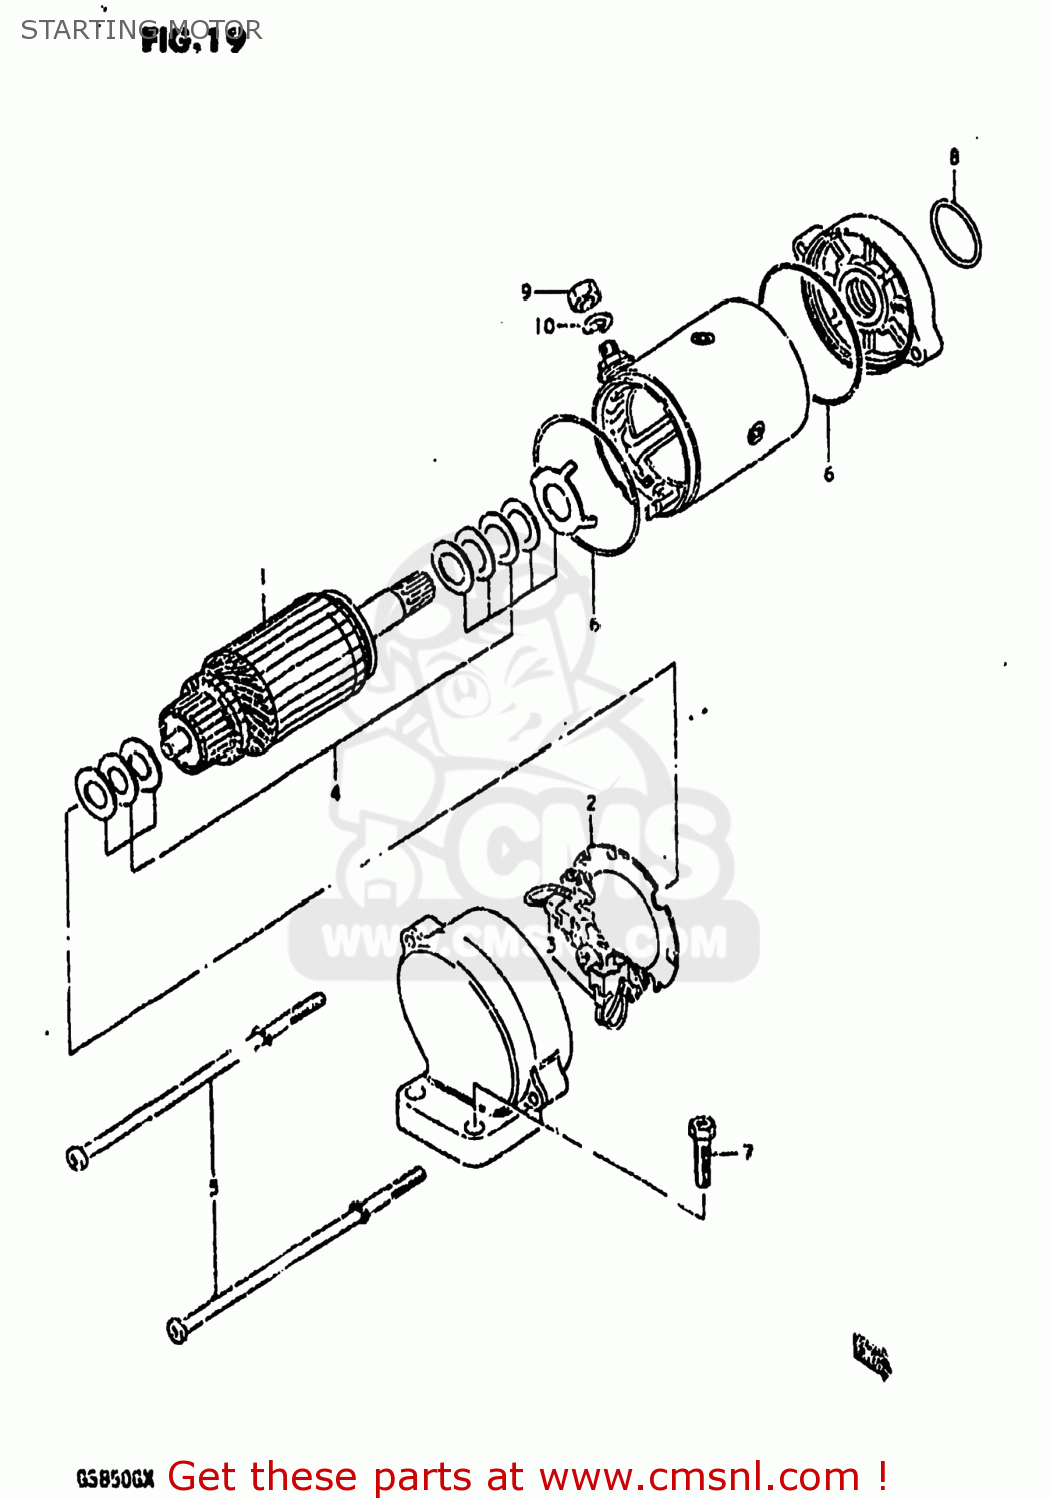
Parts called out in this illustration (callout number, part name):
1	ARMATURE
2	HOLDER ASSY
3	BRUSH SET
4	SHIM SET
5	BOLT,STARTING MOTOR HOUSING
6	O RING
7	SCREW (6X25)
8	O RING(D:2,ID:24.5)
9	NUT 6MM
10	LOCK WASHER
